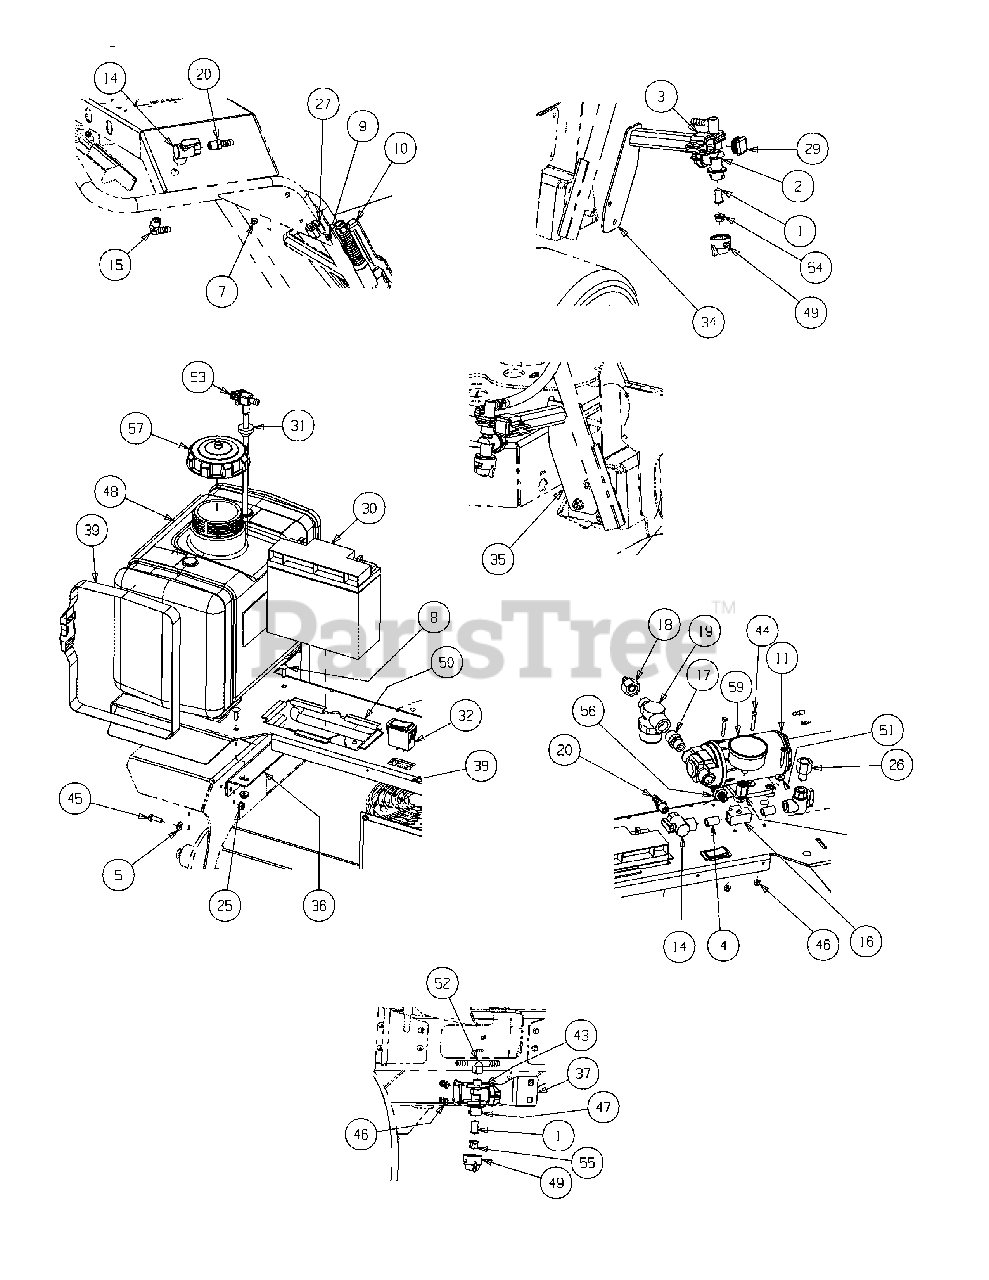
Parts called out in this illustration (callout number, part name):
1	Strainer Screen, 50 Mesh, SS
2	Single Dry Boom Nozzle Body
3	Nozzle Body Clamp, 1" SQ.
4	1/4" Brass Nipple
5	Washer, 1/4
7	Nut, #10-32, Nylon Insert
8	Carriage Bolt, 1/4-20 x .75
9	Phillips Head Screw, 10-32
10	Spray Wand
11	Pump, Flojet 25 GL
14	Valve, 1/4 90 Deg. Female
15	Fitting, 1/4 MPT x 3/8
16	Tee, 3/8 NPTF, Brass
17	Fitting, 8-145-00, Shurflo
18	Fitting, 8-060-01, Shurflo
19	Filter, 170-061-00, Shurflo
20	Fitting, 1/4 MET x 3/8 Barb, nylon
25	Nut, #10-24, Hex Flange Lock
26	Adaptor, 3/8 FNPT, 1/4 MNPT
29	Plastic Plug
30	Battery, 12CE18
31	Fuel Tank Grommet
34	Bracket Assembly, LH Nozzle
35	Bracket Assembly, RH Nozzle
38	Mounting Plate
39	Fuel Tank Mounting Strap
43	U-Bolt, #10-24
44	HHCS, #10-24 x 1.25
45	HHCS, 1/4-20 x .75
46	Nut, #10-24, Hex Flange Nylon
47	Nozzle Body, Center
48	Tank, 5 Gallon
49	Cap, Nozzle Body
50	Battery Edge Trim
51	Washer, .194 x .62 OD x .063
52	Tee Fitting, 1/4 NPTF x 3/8
53	Fitting, Sprayer Pickup
54	Fitting, Off Center Spray Tip
55	Fitting, Flat Spray Tip
56	Fitting, 3/8 NPTF x 1/4 NPTF
57	Fuel Cap
59	Pressure Gauge, 0-100 psi
